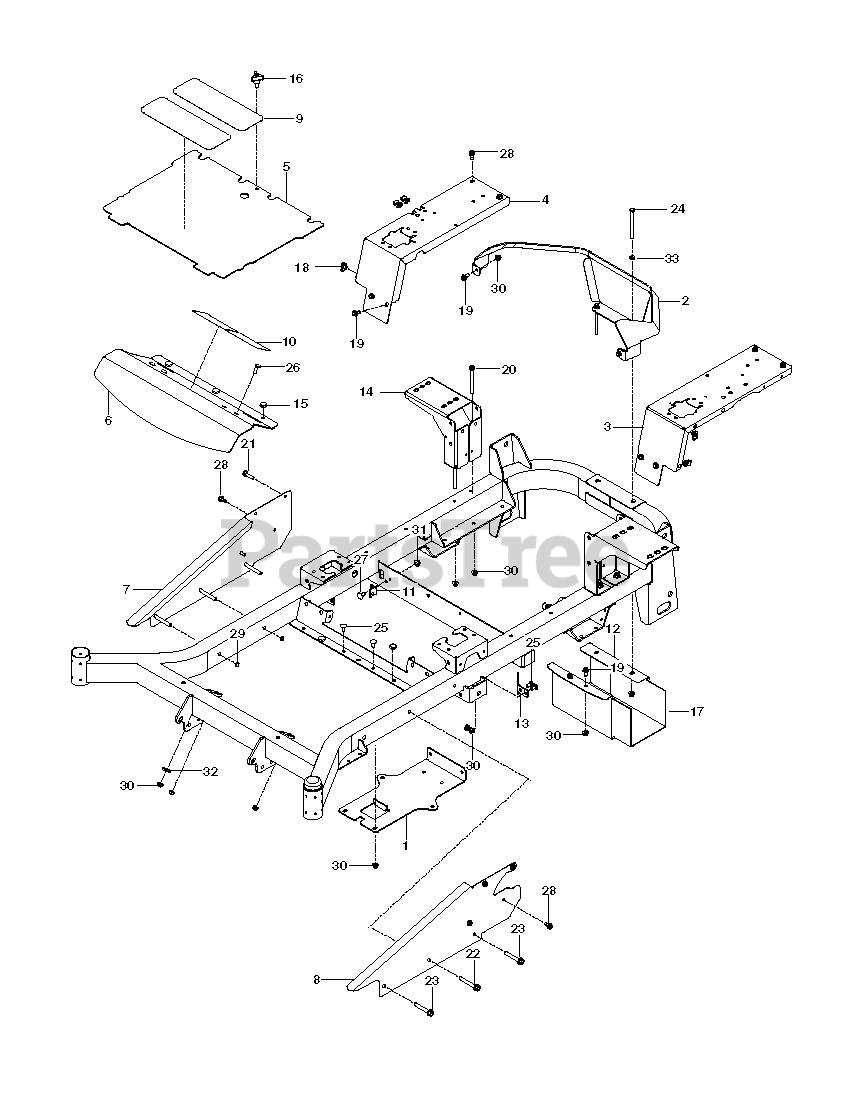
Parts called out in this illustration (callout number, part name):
1	PLATE, BATTERY, BLACK
2	GUARD, REAR MZ, GRAY
3	PANEL.FILLER.LT.ORANGE
4	PANEL.FILLER.RT.ORANGE
5	PLATE, FLOOR W/DECALS
6	PLATE, FOOTREST
7	SIDE.RT.ORANGE
8	SIDE.LT.ORANGE
9	ANTI-SKID PAD
11	BRACKET.DAMPENER.BLACK
12	SHIELD.MUFFLER.BLACK
13	STOP, DECK, EZ+
14	MOUNT, TANK, ZT BLK
15	GROMMET, BUMPER
16	KNOB W/STUD
17	HEAT SHIELD
18	U-CLIP 5/16-18 NUT RETAINER
19	HHFS 5/16-18 X 3/4
20	HHFS 5/16-18 X 3 3/4
21	HHFS 5/16-18 X 1.25 TPBLT GD 5
22	HHFS 3/8-16 X 2 3/4
23	HHFS 3/8-16 X 2.5 GR 5 ZD
24	HCS 5/16C X 4
25	BOLT 5/16C X 3/4" CARRIAGE
26	RHSNB 5/16C X 1
27	RHSNB 3/8-16 X 3/4 GR 5 BLK ZN
28	BOLT 5/16-18 X 3/4
29	NUT HEX 3/8-16 NYLON, THIN
30	5/16-18 NYLOC FLANGE NUT
31	NUT 3/8-16 HEX FLG NYLOC ZD
32	WASHER 1/2" FLAT
33	FLAT WASHER 5/16 SAE
